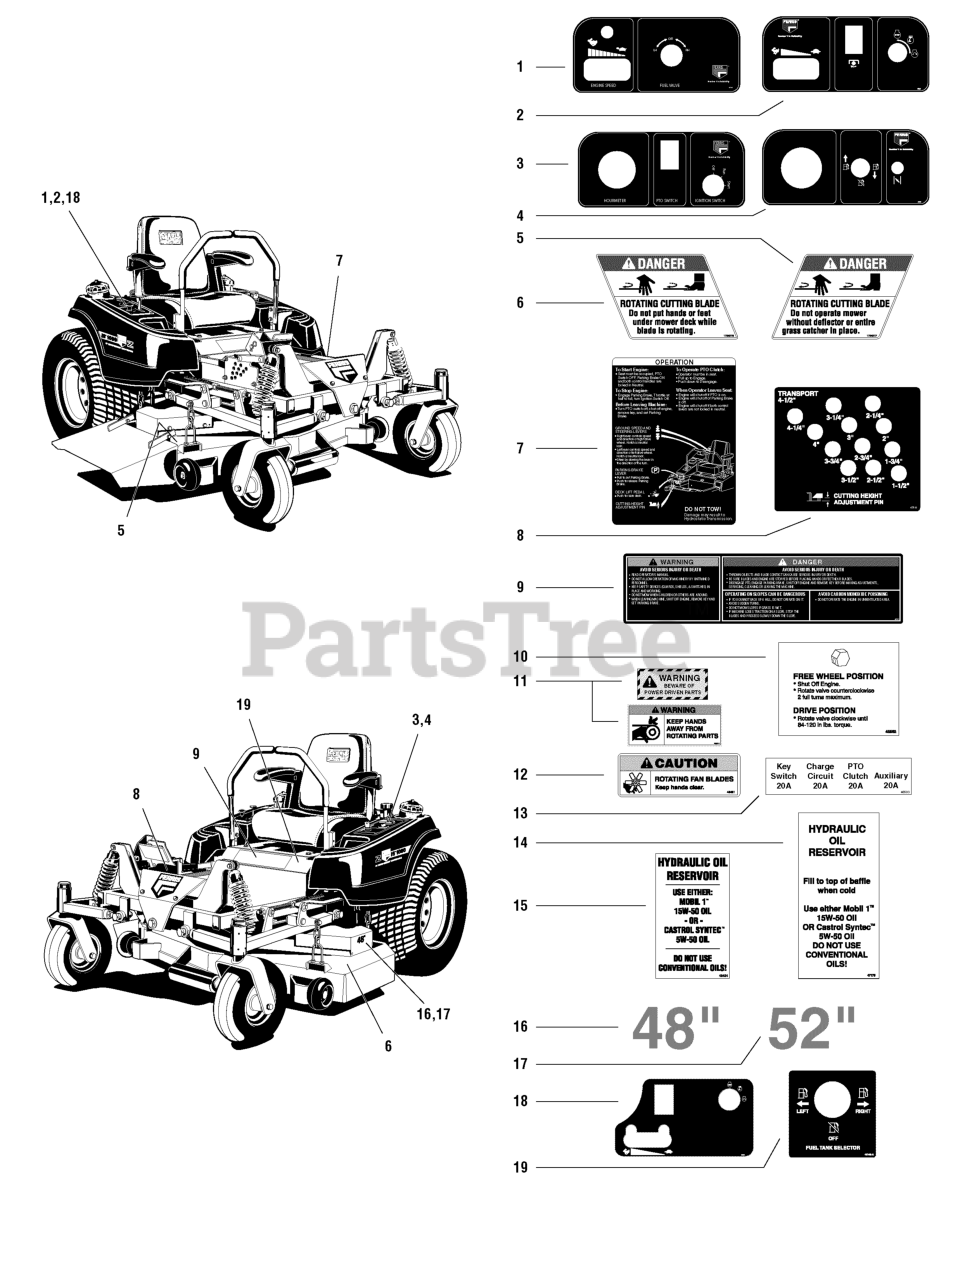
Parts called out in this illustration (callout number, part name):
1	DECAL, Control Panel-RH
2	DECAL, Control Panel-RH
3	DECAL, Control Panel-LH
4	DECAL, Control Panel-LH
5	DECAL, Danger (Chute In Place)
6	DECAL, Danger (Hand Under Deck)
7	DECAL, Operation
8	DECAL, Lift Plate
9	DECAL, Safety/Instruction
10	DECAL, Hydro Release Valve
11	DECAL, Warning
12	DECAL, Caution Fan
13	DECAL, Fuse Location
14	DECAL, Oil Reservoir
15	DECAL, Oil Reservoir
16	DECAL, 48
17	DECAL, 52
18	DECAL, Control Panel
19	DECAL, Fuel Selector
